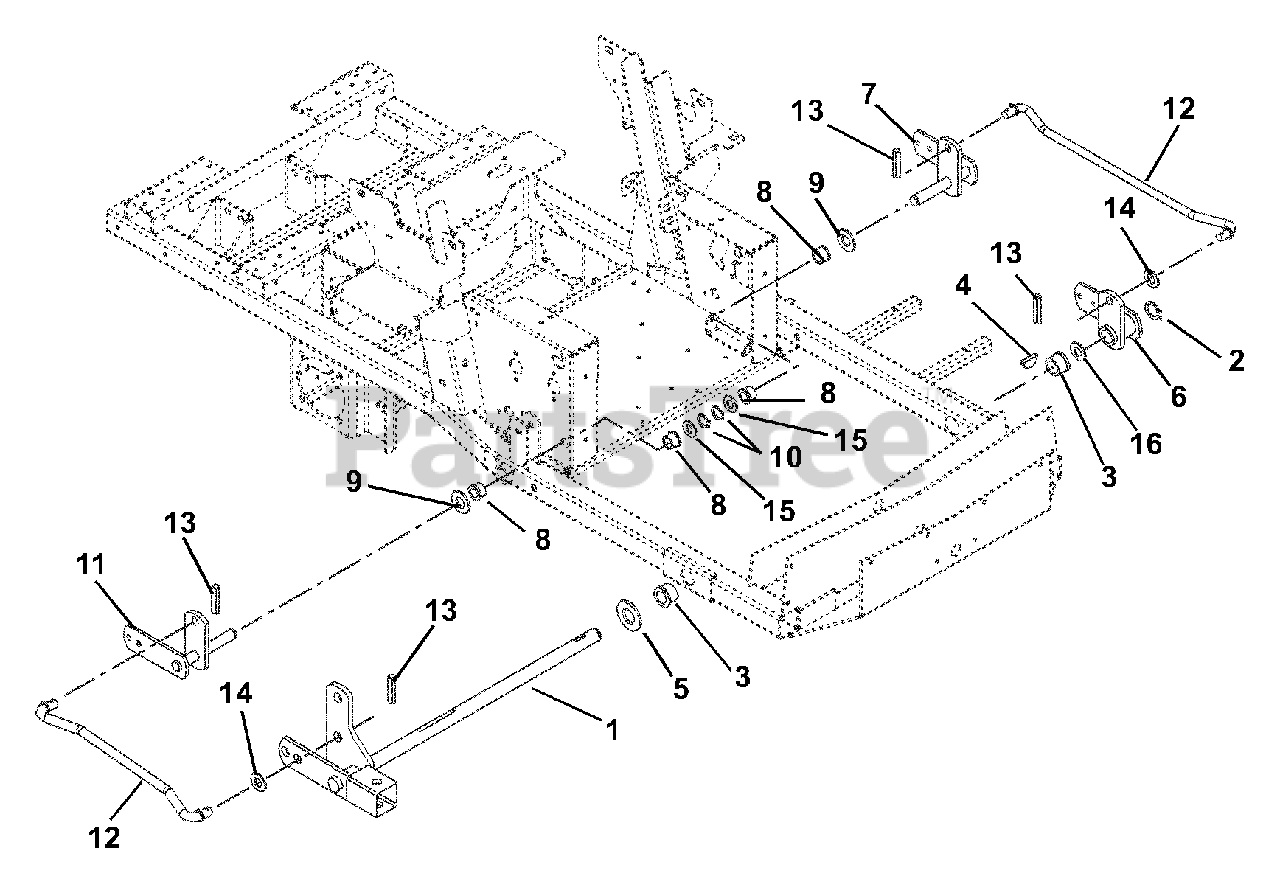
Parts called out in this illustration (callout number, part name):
1	Lift, Mower
2	Ring, Retaining External 1.00 x .078
3	Bushing, Flange Nylon 1.02 x 1.385 x .75 x 1.75
4	Key, Woodruff .25 x 1.00
5	Washer, Flat Steel 1.063 x 2.00 x .134
6	Weldment, Lift Arm-Front
7	Weldment, Rear Lift Arm-Left Hand
8	Bushing, Flange Nylon .762 x 1.0 x .58 x 1.48
9	Washer, Hardened Steel .758 x 1.23 x .031
10	Ring-Retaining-External .689 x .077
11	Weldment, Rear Lift Arm- Right Hand
12	Rod, Lift Assist 19.35"
13	Pin, Roll .25 x 1.25 Stainless Steel
14	Washer, Flat Steel .630 x 1.25 x .062
15	Washer, Flat Steel .755 x 1.25 x .125
16	Washer, Hardened Thrust 1.00 x 1.55 x .03
